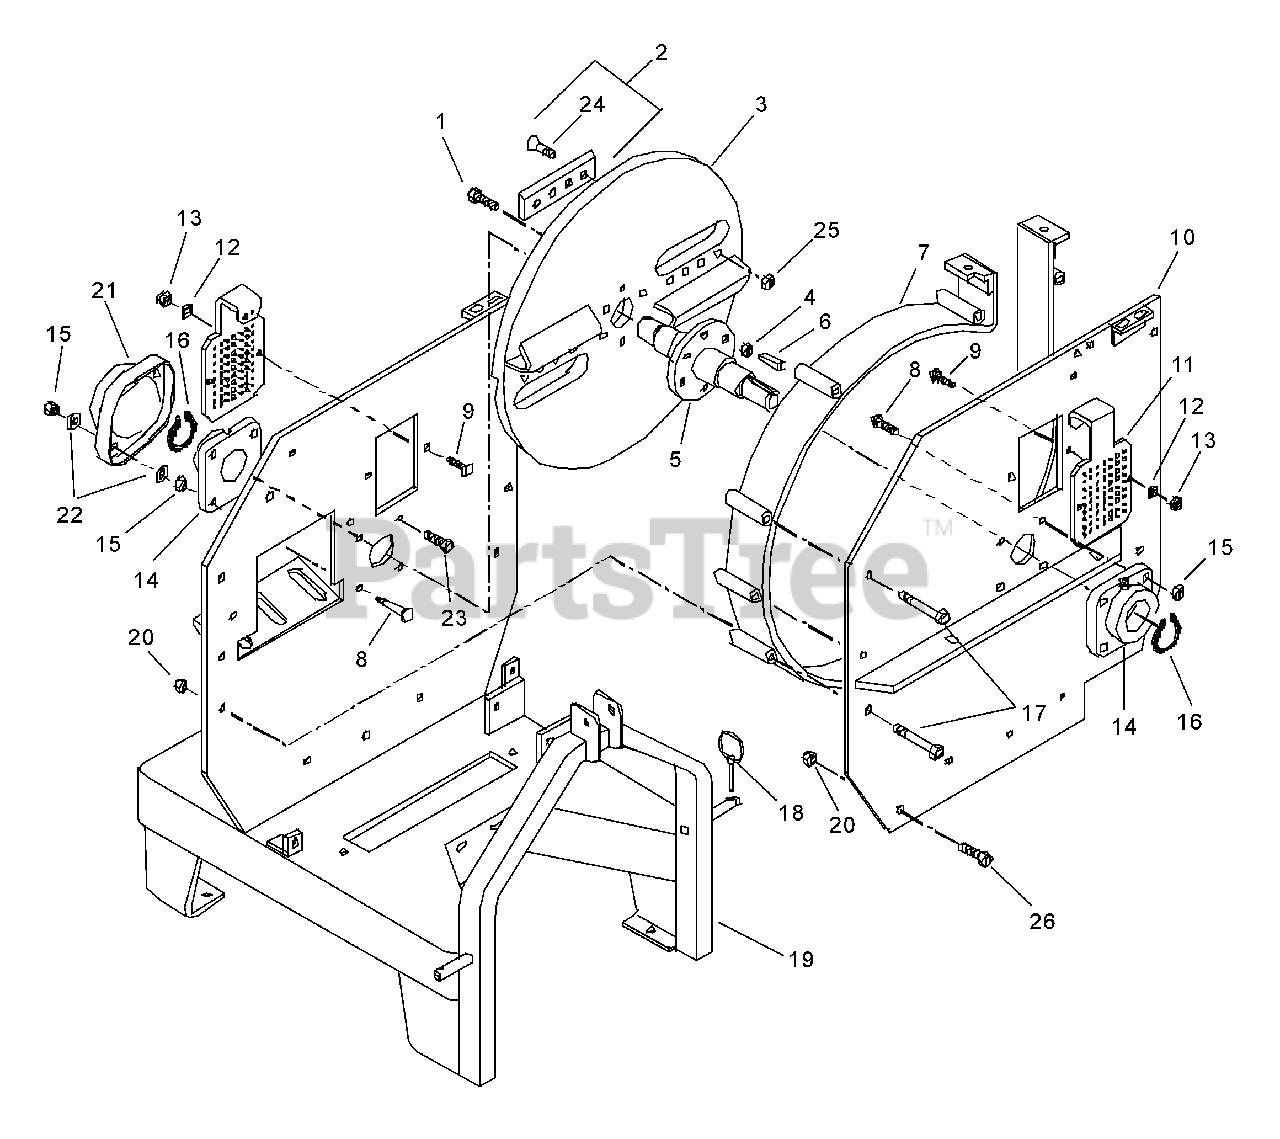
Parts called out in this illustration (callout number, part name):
1	Bolt-Hex .50-13 x 2.00 Grade 5
2	Chipper Knife Kit 210/PTO
3	Flywheel PTO
4	Nut-Locking-Center .50-13
5	Arbor Shaft
6	Key-Straight .38 x 2.0 x .38
7	Ring-Flywheel Housing Drum
8	Bolt-Lug .50-20 x 1.50
9	Bolt-Carriage Special Rib .38-16 x 1.0
10	Plate-Flywheel Housing Side
11	Plate-Knife Access
12	Washer-Lock .375 x .155
13	Nut-Hex .38-16
14	Four Hole Flange Bearing
15	Nut-Locking-Center .50-20
16	Ring-Retaining-External 1.500 x .109
17	Bolt-Hex .38-16 x 5.75
18	Yoke Pin
19	Frame - PTO Pro Chip Weldment
20	Nut-Locking-Center .38-16
21	Bearing Cover
22	Washer-Flat-Steel .531 x 1.06 x .095
23	Bolt-Lug .50-20 x 2.50
24	Bolt-Flat Socket Head .50-13 x 1.75 Grade 8
25	Nut-Locking .50-13 Grade C
26	Bolt-Hex .38-16 x .75 Grade 5
